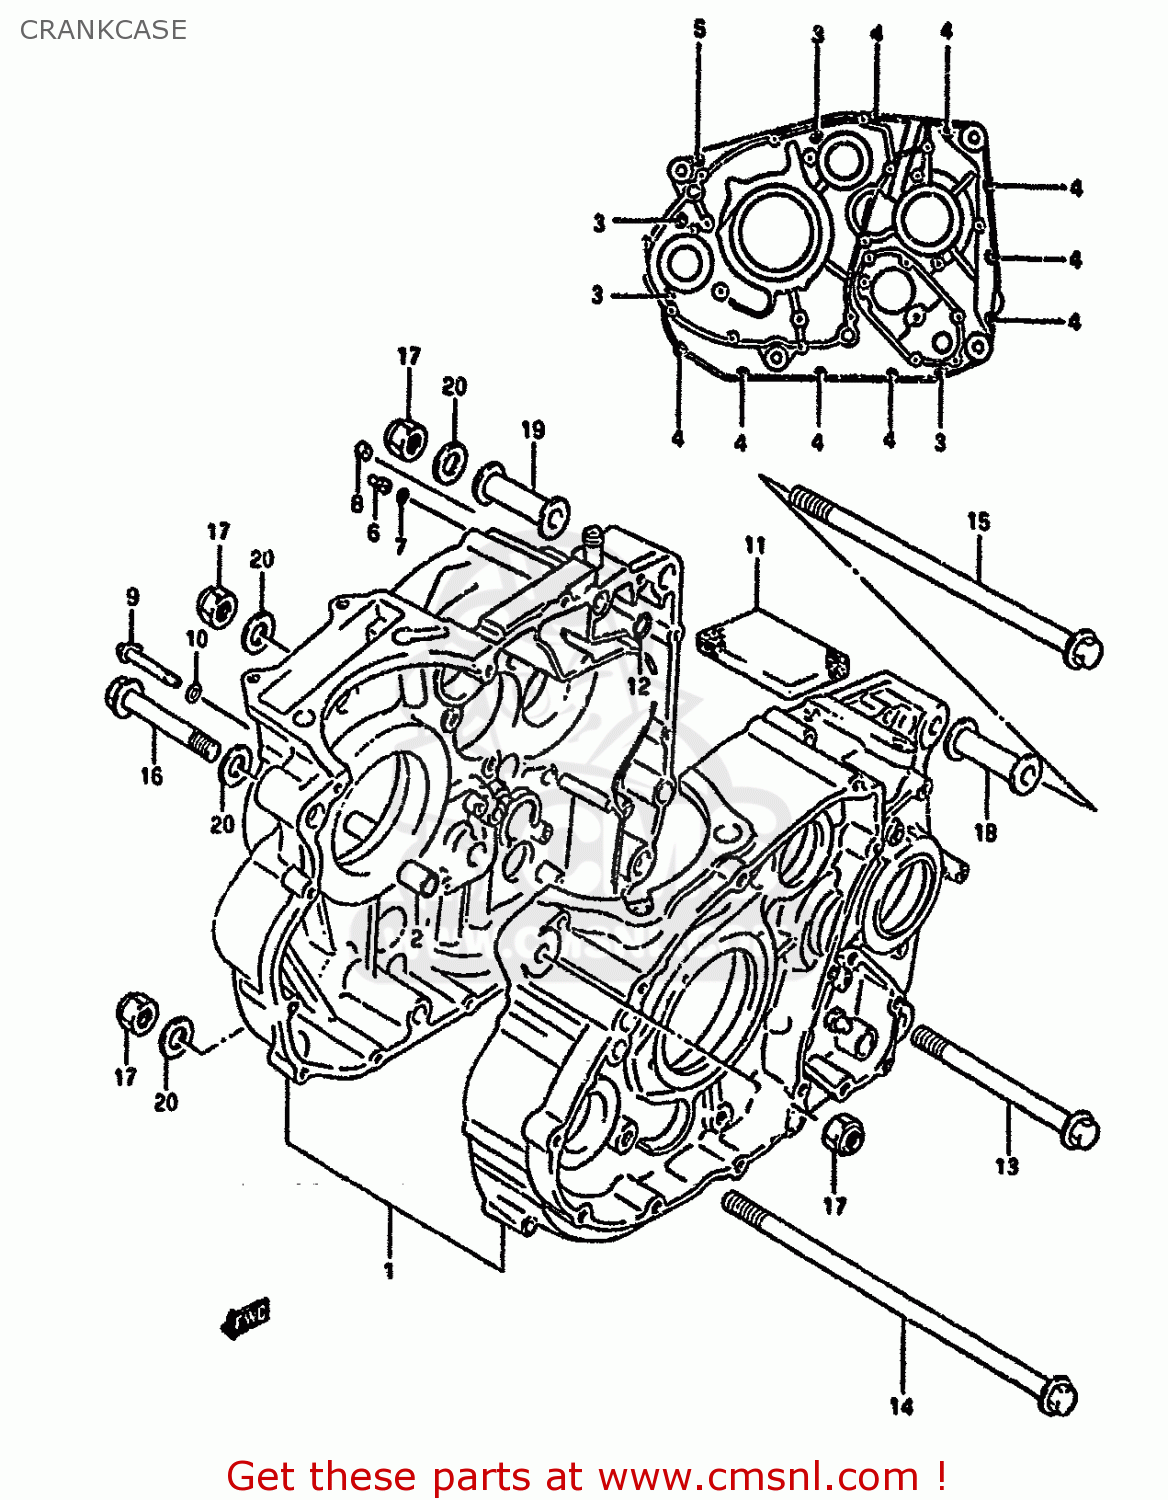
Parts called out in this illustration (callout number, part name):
1	CRANKCASE SET
2	PIN
3	BOLT
4	BOLT
5	BOLT
6	JET(12)
7	O RING(D:1.2,ID:4)
8	JET,OIL GALLERY
9	PIPE,PISTON COOLING
10	O RING(D:1.9,ID:7.8)
11	SEPARATOR,OIL BREATHER
12	O RING(D:1.9,ID:8.6)
13	BOLT(10X130)
14	BOLT 10X230
15	BOLT(10X235)
16	BOLT(10X80)
17	NUT (10MM)
18	SPACER,ENG MTG(L:55)
19	SPACER,ENGINE MOUNT(L:65)
20	WASHER
